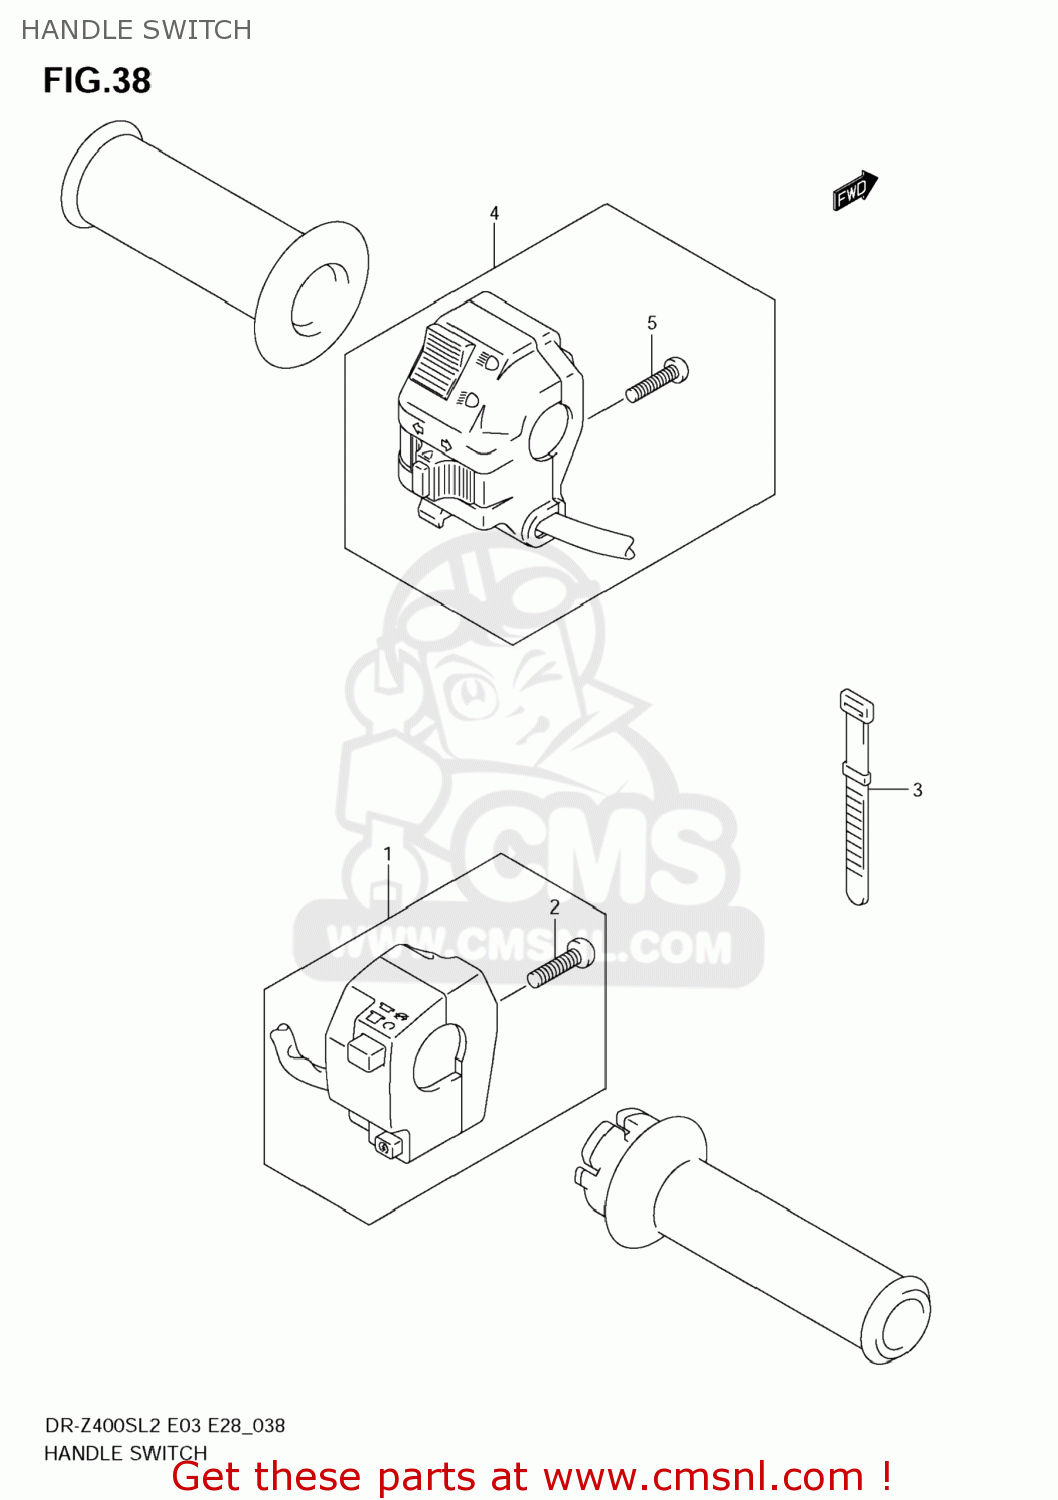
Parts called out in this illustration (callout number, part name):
1	SWITCH ASSY,HANDLE,R
2	SCREW
3	CLAMP(L:120)
4	SWITCH ASSY,HANDLE,L
5	SCREW
